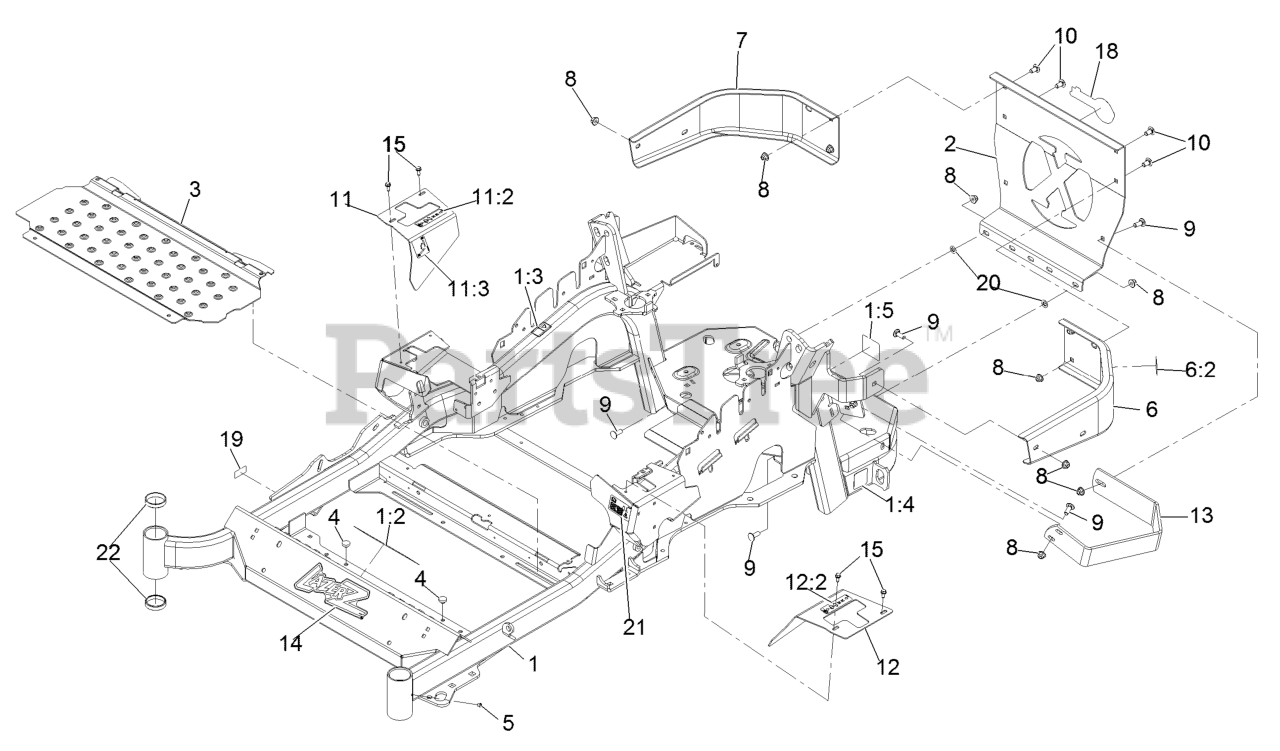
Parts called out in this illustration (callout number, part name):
1	MAINFRAME ASM
1:2	DECAL-WARNING, SLOPE
1:3	DECAL-WARNING
1:4	DECAL-HAZARD, PINCHED FINGER
1:5	DECAL-SPARK ARRESTER
2	PLATE,REAR GUARD
6	LH BUMPER ASM
6:2	DECAL-WARNING
7	BUMPER-RH
8	NUT-HF, NI
9	SCREW-CARR
10	SCREW-CARR
11	RH MOTION CONTROL COVER ASM
11:2	DECAL-CONTROL, MOTION
11:3	DECAL-PARK BRAKE, CE
12	LH MOTION CONTROL COVER ASM
12:2	DECAL-CONTROL, MOTION
13	GUARD-MUFFLER
14	DECAL,LAZER MODEL
15	SCREW-HWH
19	Decal-Patent Ttco.Com
20	NUT-PUSH
21	DECAL-FUEL FILL, CE
22	CUP-BEARING
